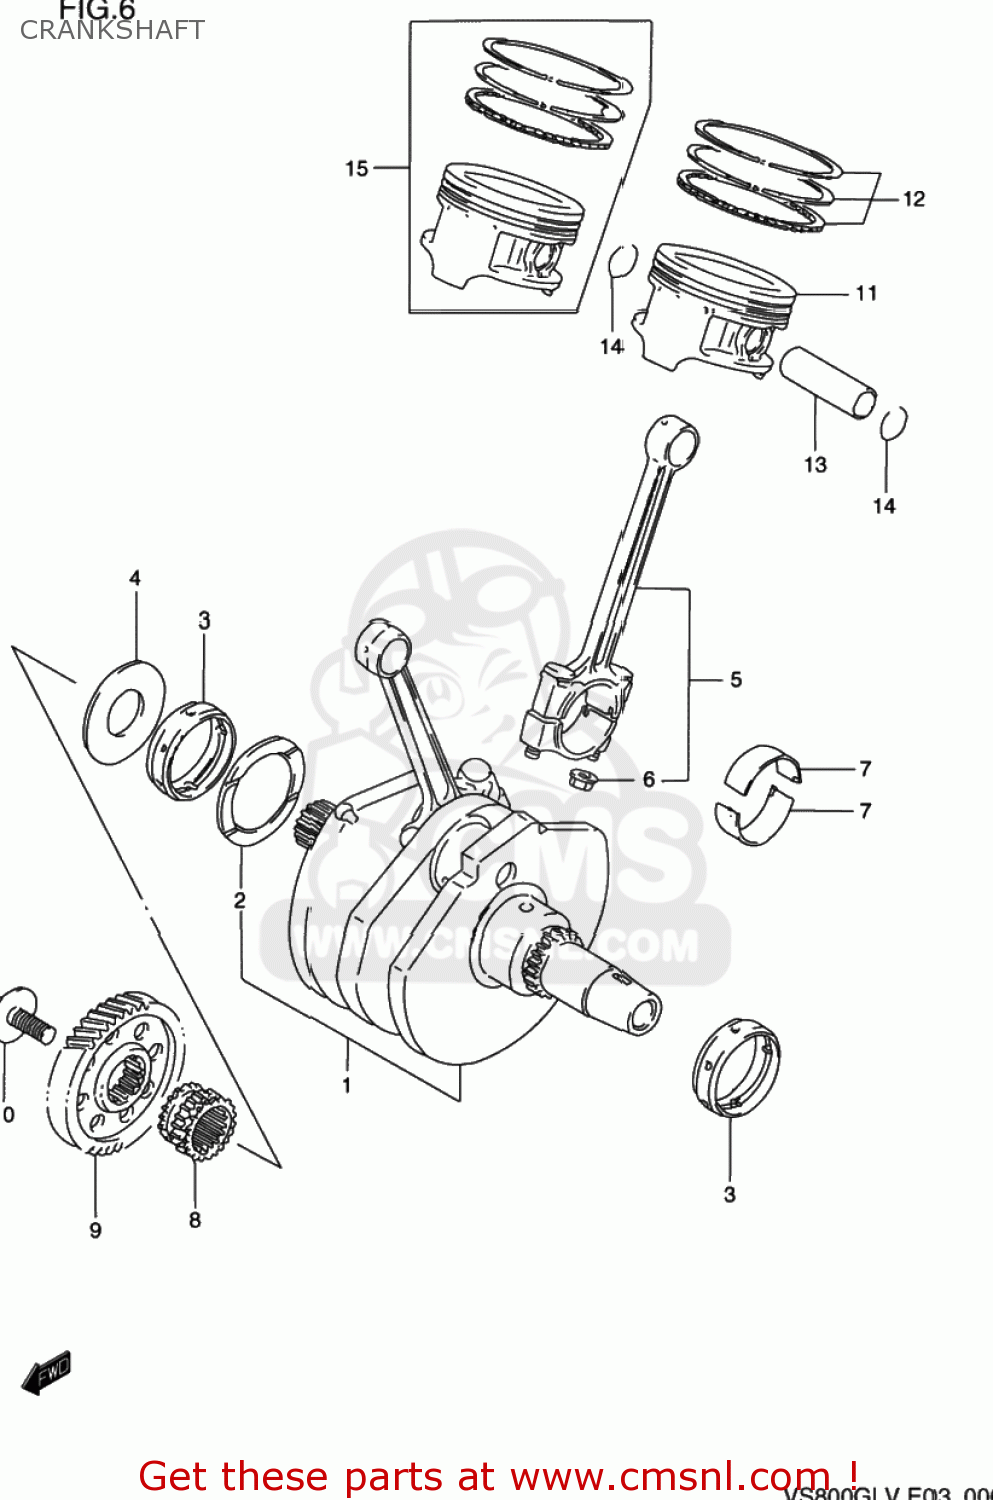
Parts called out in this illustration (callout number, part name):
1	CRANKSHAFT SET
2	WASHER(48.1X64X1.94)
3	METAL,CRANKSHAFT
4	WASHER,CRANK THRUST
5	CONNECTING ROD ASSY
6	NUT
7	BEARING,CRANK PIN
8	SPROCKET,CAM CHAIN DRIVE,R
9	GEAR,PRIMARY DRIVE
10	BOLT(12X28)
11	PISTON
12	RING SET,PISTON
13	PIN,PISTON
14	CIRCLIP,PISTON PIN
15	PISTON SET(OS:0.5)
